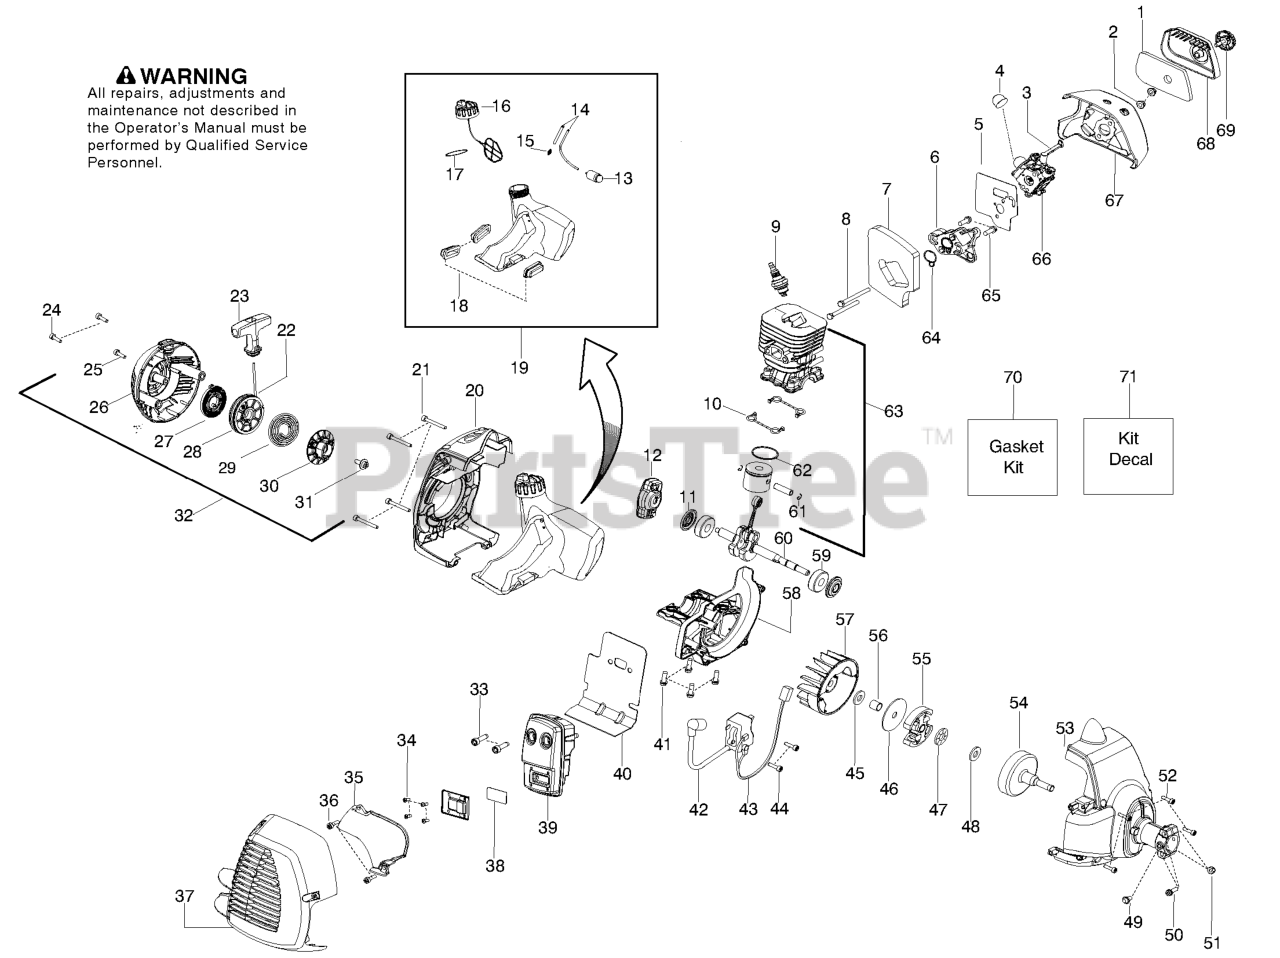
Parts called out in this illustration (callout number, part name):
1	FILTER AIRBOX
3	CHOKE LEVER
4	PURGE BULB ZAMA
5	KIT GASKET CARB 28CC
6	CARB ADAPTOR
7	KIT GASKET 28CC
8	BOLT CARB ADAPTOR
9	Plug - Spark (RCJ-8Y)
10	KIT GASKET 28CC
11	KIT GASKET 28CC
12	STARTER PAWL BRIDGE
13	FUEL PICK-UP ASSY
14	KIT-LINE(FUEL)
15	FUEL LINE FITTING
16	ASSY-CAP W/RETAINER
17	KIT GASKET 28CC
18	ISOLATOR FUEL TANK
19	KIT FUEL TANK HVA
20	KIT STARTER HSG HVA 128
22	KIT ROPE
23	HANDLE - STARTER
24	SCREW M5-0.8X30MM
25	SCREW M4 X 1.75 PT 16MM
26	KIT STARTER HSG HVA 128
27	KIT STARTER SPRING
28	KIT STARTER PULLEY
29	SPRING - DRIVER
30	DRIVER PULLEY
32	ASSY STARTER HSG HVA
33	BOLT MUFFLER
34	SCREW-6-19X5/16PLAST PA
35	SHIELD HEAT
36	SCREW M4 X 1.75 PT 16MM
37	KIT MUFFLER GUARD HVA
38	KIT SPARK ARRESTOR SCREEN
39	KIT MUFFLER LE28
40	KIT GASKET 28CC
41	SCREW-M5-0.8 X 25MM(TAP)
42	IGNITION MODULE MBU-7
43	ASSY MODULE LEAD WIRE
44	SCREW M4 X .70 TT 16MM
45	WASHER CLUTCH
46	WASHER-CLUTCH
47	BEARING THRUST
48	WASHER THRUST
49	Screw
50	Screw
51	LOCKNUT-HEX 10-24
52	SCREW M4 X .70 TT 16MM
53	Assy - Fan Housing
54	ASSY-CLUTCH DRUM
55	ASSEMBLY CLUTCH
56	SPACER FLYWHEEL
58	CRANKCASE CAST LE28
59	BEARING RADIAL BALL (6201)
60	ASSY CRANKSHAFT
61	WRIST PIN RET.
62	RING PISTON
63	KIT PISTON & CYLINDER
64	KIT GASKET 28CC
65	SCREW-M5-0.8 X 25MM(TAP)
66	KIT CARB
67	RP_AIR BOX
68	COVER-AIR BOX
69	KNOB ASSY AIRBOX COVER
70	KIT GASKET 28CC
